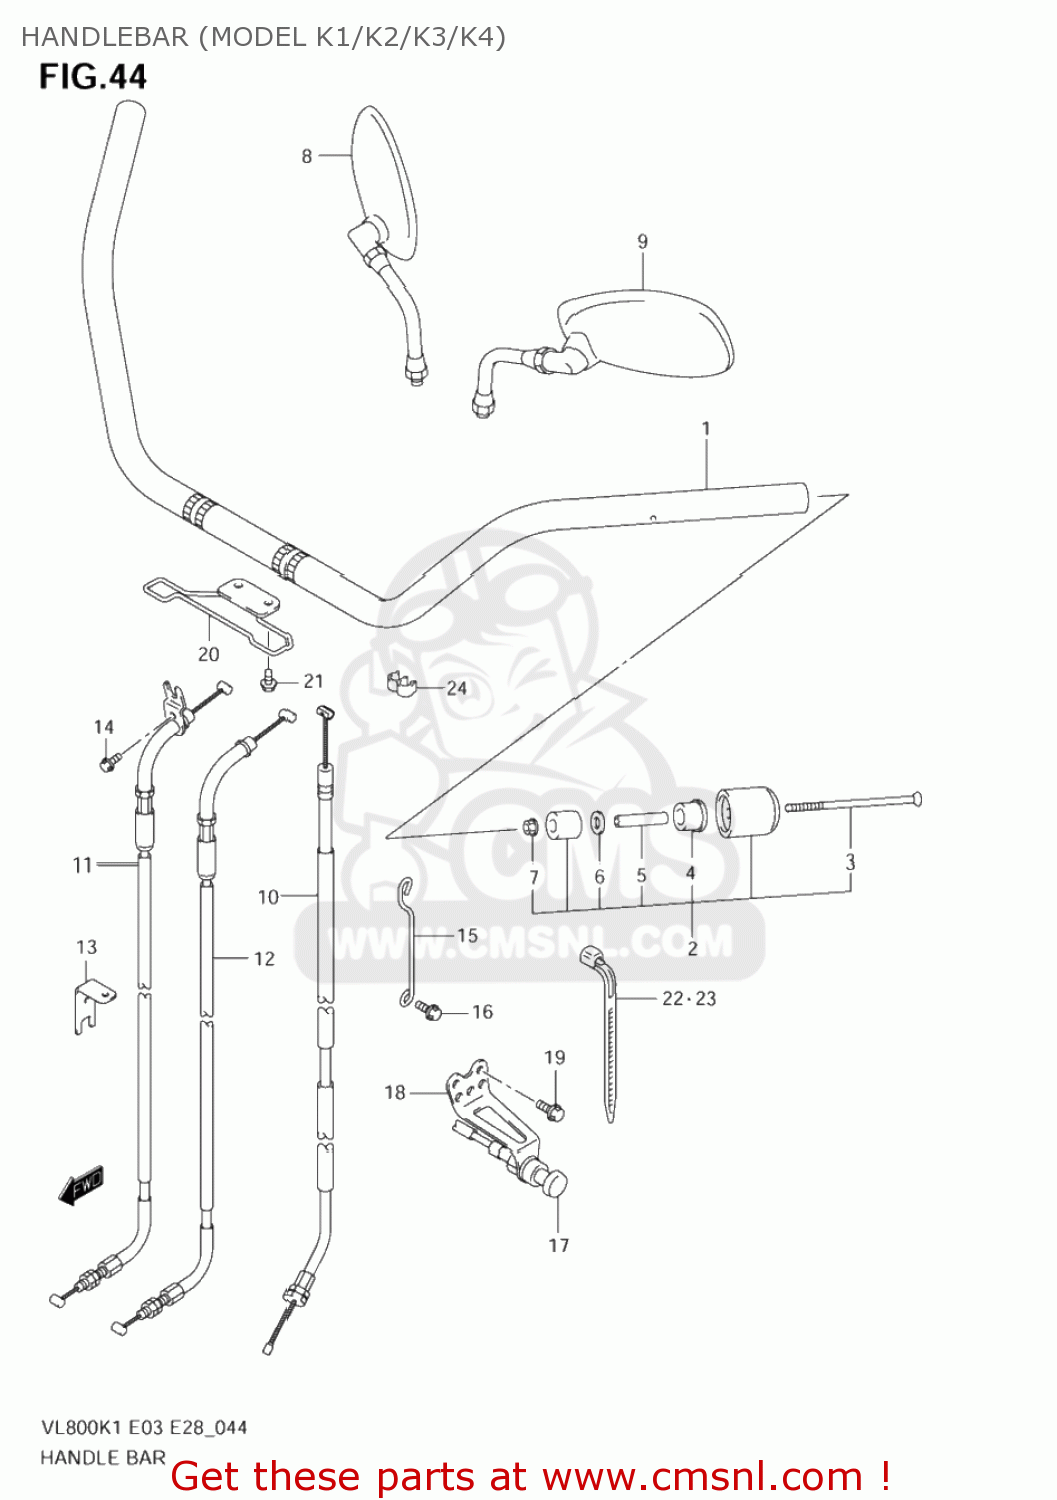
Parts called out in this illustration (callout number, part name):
1	HANDLEBAR
2	BALANCER SET,HANDLEBAR
3	SCREW(6X127)
4	EXPANDER,HANDLE BALANCER NO.2
5	SPACER,EXPANDER
6	WASHER(6.5X18X2)
7	NUT
8	MIRROR ASSY,RE
9	MIRROR ASSY,RE
10	CABLE ASSY,CLUTCH
11	CABLE ASSY,THROTTLE
12	CABLE ASSY,THROTTLE NO.2
13	PLATE,THROTTLE CABLE
14	BOLT
15	GUIDE,THROTTLE CABLE
16	SCREW(5X10)
17	CABLE,STARTER
18	BRACKET,STARTER CABLE
19	BOLT
20	GUIDE,CABLE
21	BOLT
22	CLAMP(L:190)
23	CLAMP(L:235)
24	CLAMP
